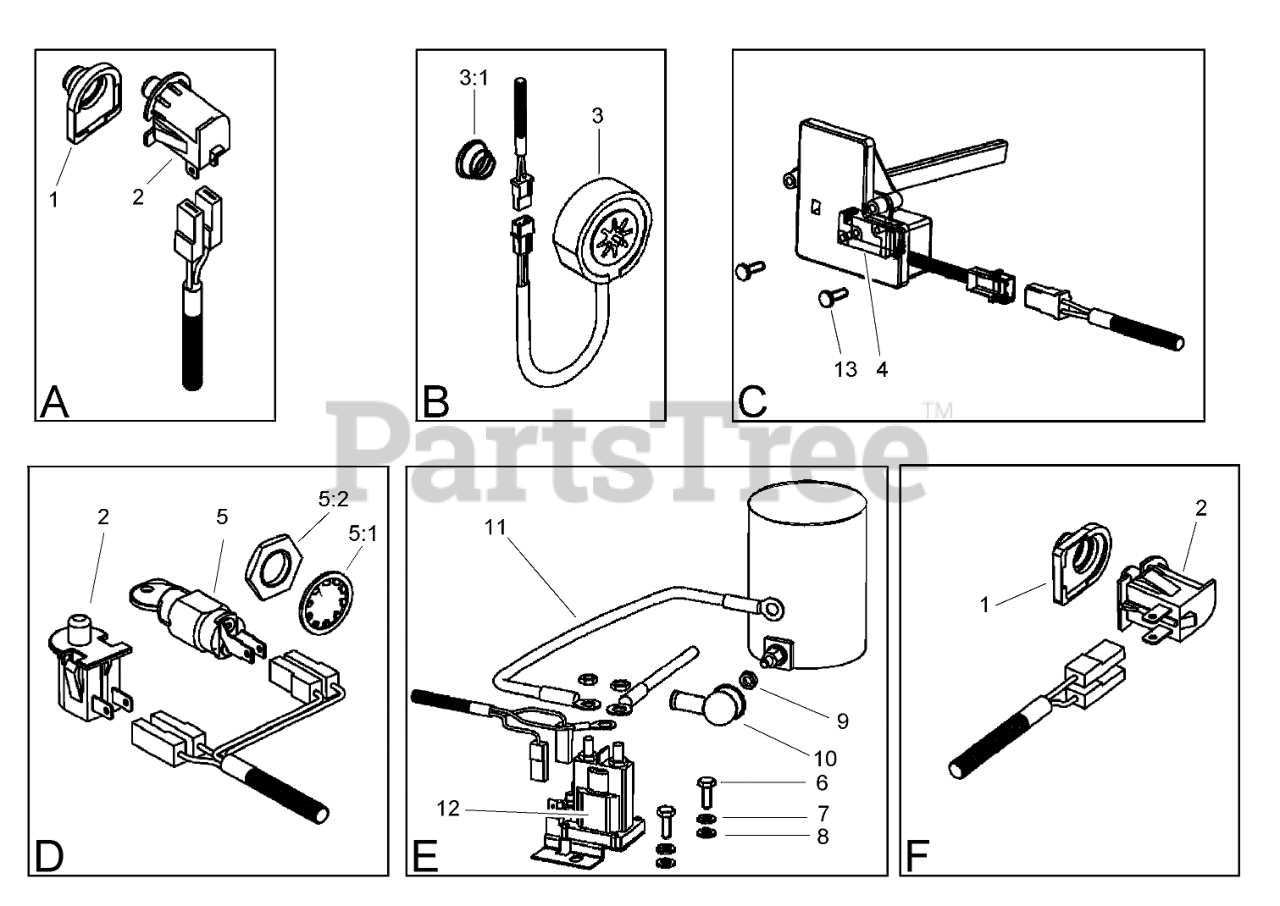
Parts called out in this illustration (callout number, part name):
1	COVER-PROTECTIVE
2	SWITCH-DELTA
3	MAGNET ASM
3:1	SPRING-COMPRESSION
4	SWITCH-OMRON
5	STARTER SWITCH ASM
5:1	WASHER-TOOTH, INTERNAL
5:2	NUT-HH
6	SCREW-HH
7	WASHER-SPRING
8	WASHER-FLAT
9	NUT-HHF
10	BOOT-RUBBER
11	LEAD-STARTER, ELECTRIC
12	Solenoid
13	Screw
